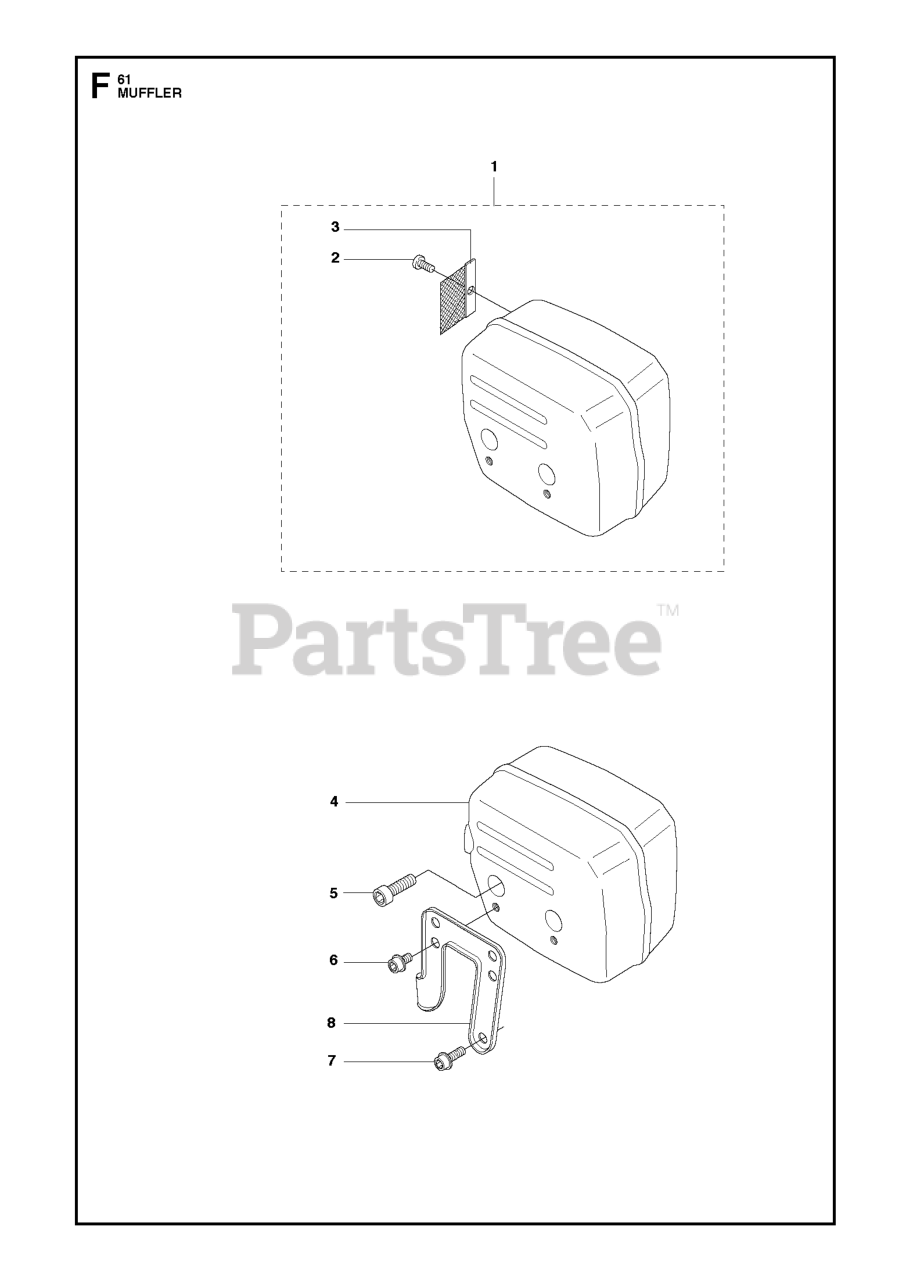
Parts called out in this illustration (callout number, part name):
1	MUFFLER
4	MUFFLER
5	SCREW MC6S 6X20
6	SCREW
8	SUPPORT
